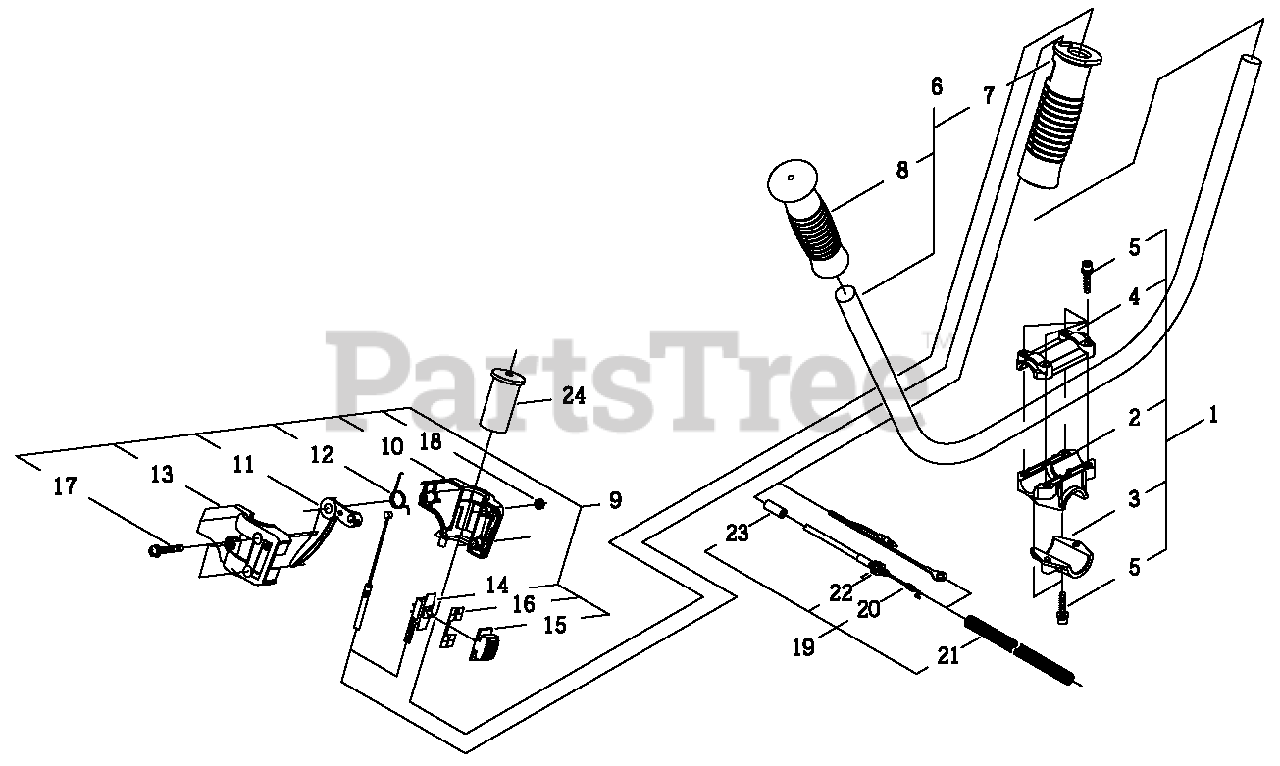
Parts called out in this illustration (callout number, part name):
1	BRACKET KIT, HANDLEBAR
2	BRACKET, LOWER HANDLEBAR
3	BRACKET, MOUNTING
4	BRACKET, UPPER HANDLEBAR
5	BOLT M5×25
6	HANDLEBAR ASSY
7	GRIP, THROTTLE
8	GRIP
9	THROTTLE CONTROL ASSY
10	CONTROL HANDLE - RIGHT
11	TRIGGER, THROTTLE
12	SPRING, RETURN
13	CONTROL HANDLE - LEFT
14	SWITCH, ON-OFF
15	KNOB, SWITCH
16	PLATE, SWITCH
17	SCREW M5×30
18	NUT M5
19	CABLE ASSY, THROTTLE
20	CABLE, THROTTLE
21	TUBE, FLEXIBLE
22	NUT M6
23	PIPE
24	SPACER
